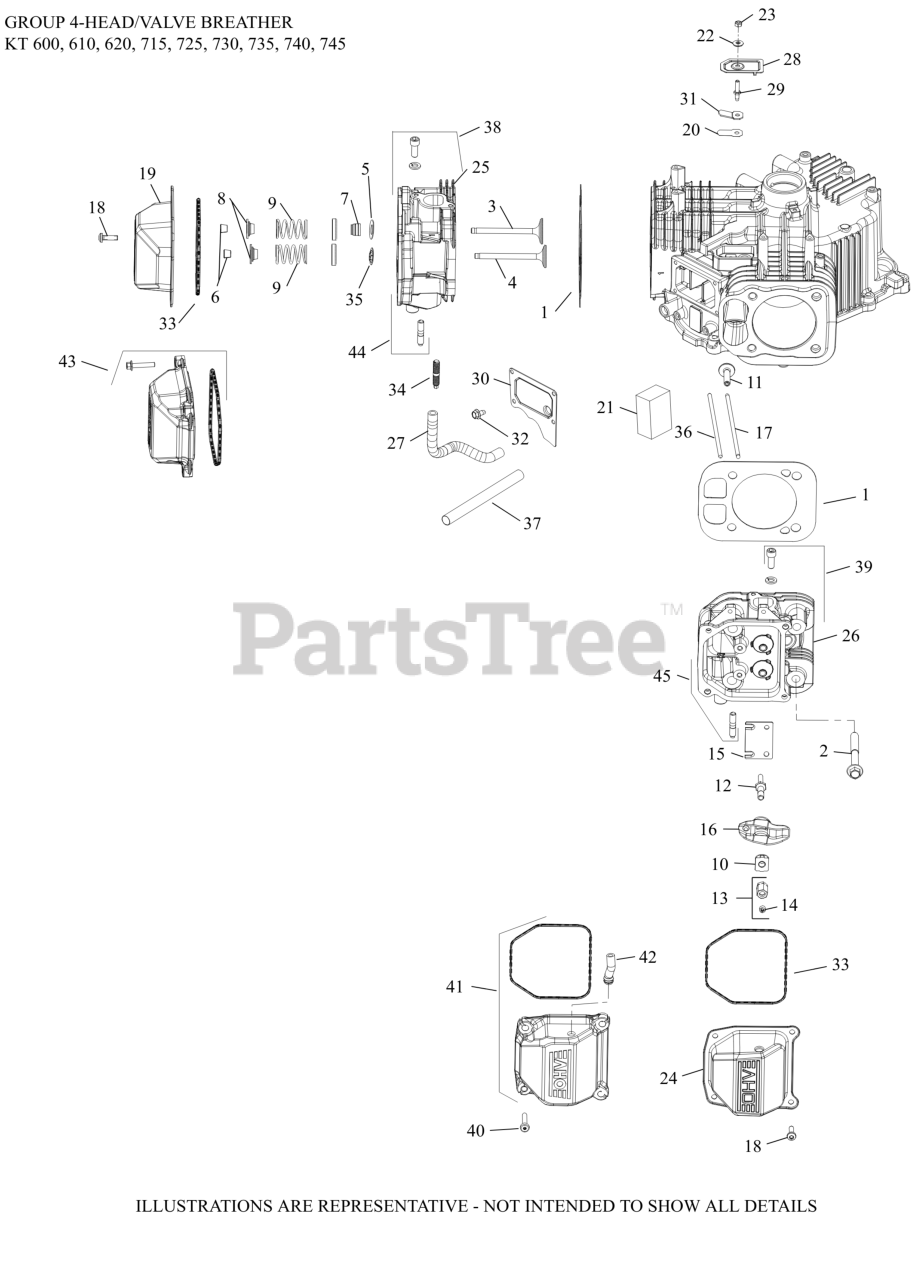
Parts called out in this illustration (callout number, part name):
1	KIT, CYLINDER HEAD GASKET
2	SCREW, FLG M10X1.5X90
3	VALVE, INTAKE
3	VALVE, INTAKE (.25) - (#2401702S)
4	VALVE, EXHAUST
4	VALVE, EXHAUST (.25)
5	SPACER (.010")
6	KIT, RETAINER
7	SEAL, VALVE BAND
8	CAP, VALVE SPRING
9	SPRING VALVE
10	PIVOT, ROCKER ARM
12	STUD, ROCKER
13	HEX NUT ASSEMBLY
14	SCREW, SET
15	PLATE, GUIDE
16	ARM, ROCKER
17	ROD, PUSH
18	SCREW, PAN HEAD
19	COVER, ROCKER STAMPED STEEL
20	REED, BREATHER
21	FILTER, BREATHER
22	WASHER, SEALING
23	NUT, LOCK M5X.8
24	COVER, ROCKER STAMPED STEEL
25	HEAD, ASSY CYL (#1)-USE 32 755 29-S
26	HEAD, ASSY CYL (#2)-(#3275530S)
27	HOSE, BREATHER
28	COVER, BREATHER REED
30	COVER, BREATHER MEDIA
31	RETAINER, REED
32	SCREW, THREAD FORMING
35	RETAINER, VALVE GUIDE (KM)
NI	KIT, #1 HEAD AND HARDWARE-(#3275539S)
NI	KIT, #2 HEAD AND HARDWARE-(#3275540S)
